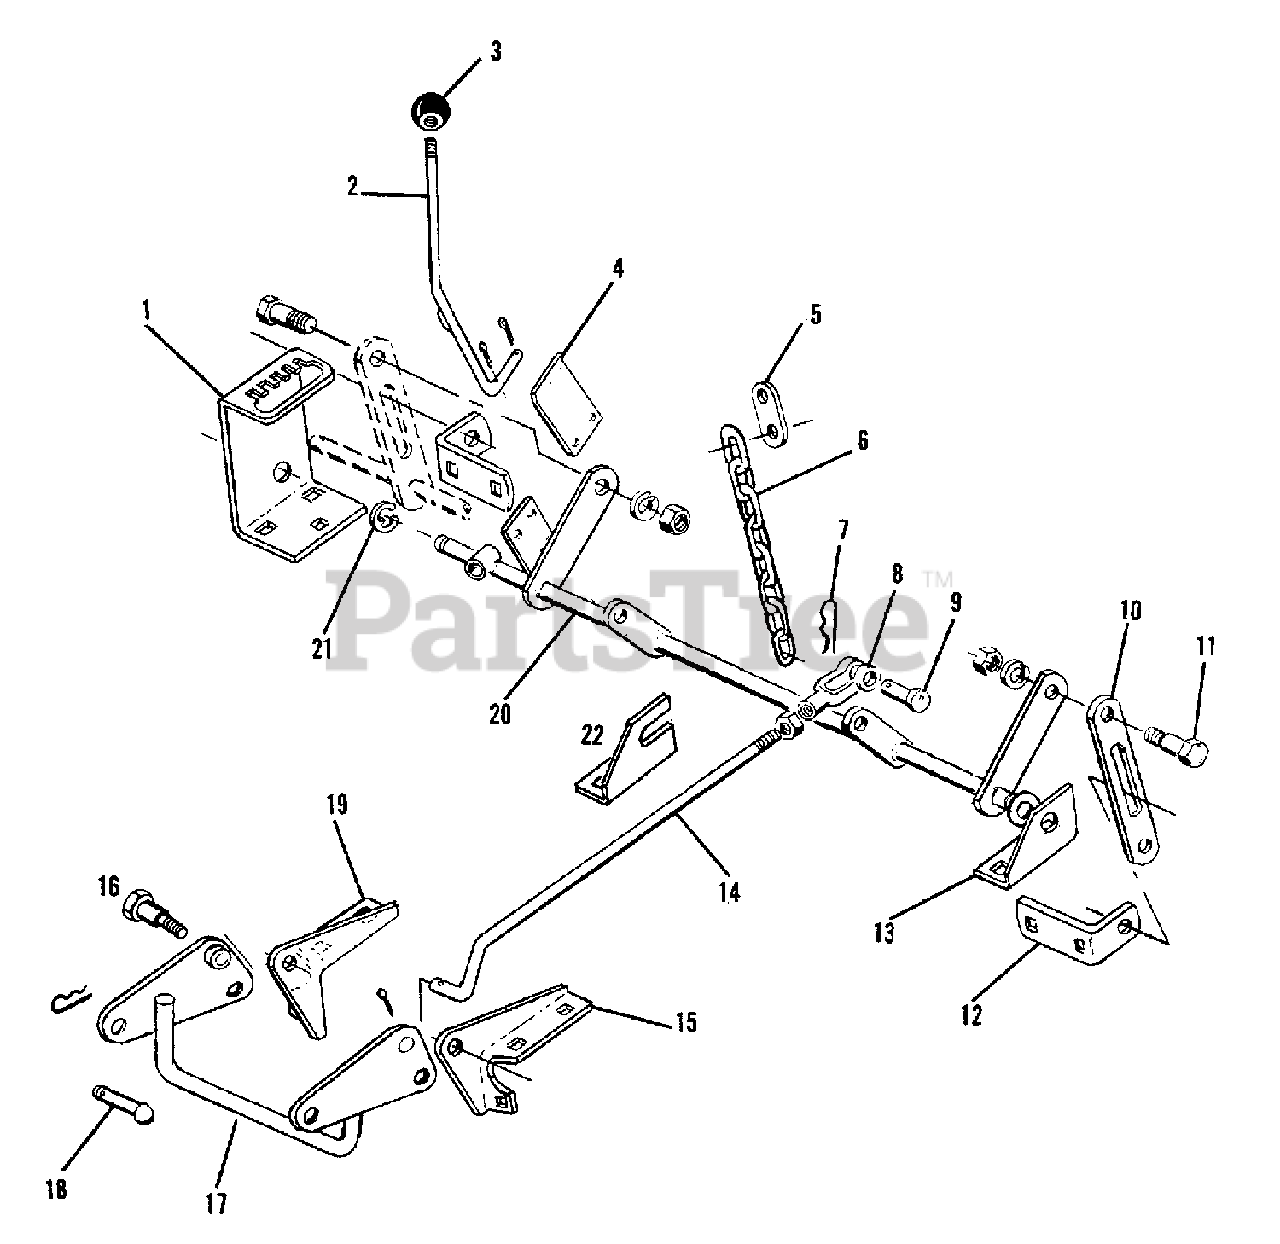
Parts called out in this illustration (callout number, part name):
1	QUADRANT, Control
1	DECAL, Quadrant
1	BOLT, Carriage, 4/8NC x 3/4
1	LOCKWASHER, 3/8
1	NUT, 3/8NC
2	LEVER, Control
2	PIN, Cotter, 1/8 x 1
3	KNOB, Control Lever
4	SPRING, Lever Retaining
4	RIVET, Pop, 3/16
5	LINK, Lift
5	CAPSCREW, 3/8NC x 1
5	WASHER, Plain, 7/16 x 1 x #14
5	NUT, Lock, 3/8NC
6	CHAIN, Lift
6	CAPSCREW, 3/8NC x 1-1/4
6	WASHER, Plain, 7/16 x 1 x #14
6	LOCKWASHER, 3/8
6	NUT, 3/8NC
7	PIN, Quick-Hitch
8	YOKE, Rod
9	PIN, Yoke
10	BAR, Roller Lift
11	BOLT, Shoulder, 3/8-16 X 1.34
11	WASHER, Plain, 1/2 x 1-1/4 x #14
11	LOCKWASHER, 3/8
11	NUT, 3/8NC
12	BRACKET, Roller Support
12	BOLT, Carriage, 3/8NC x 3/4
12	BOLT, Carriage, 3/8NC x 1
12	LOCKWASHER, 3/8
12	NUT, 3/8NC
13	BRACKET, Pivot, L.H.
14	ROD, Adjusting, R.H. (f/42" Mower)
14	ROD, Adjusting, L.H. (f/42" Mower)
14	ROD, Adjusting, R.H. (f/48" Mower)
14	ROD, Adjusting, L.H. (f/48" Mower)
14	PIN, Cotter, 1/8 x 1
14	NUT, Jam 1/2NF
15	BRACKET, Link, L.H.
15	BOLT, Carriage, 3/8NC x 3/4
15	LOCKWASHER, 3/8
15	NUT, 3/8NC
16	BOLT, Shoulder
16	NUT, 3/8NC, Lock
17	LINK ASSEMBLY, Pivot
18	PIN, Link
19	BRACKET, Link, R.H.
19	BOLT, Carriage, 3/8NC x 3/4
19	LOCKWASHER, 3/8
19	NUT, 3/8NC
20	ARM ASSEMBLY, Adjusting
20	WASHER, Plain, 25/32 x 1-1/4 x #16
21	RING, Retaining
22	BRACKET, Lift
22	BOLT, 5/16NC x 3/4
22	LOCKWASHER, 5/16
22	NUT, 5/16NC
22	PIN, Spring, .072 x 1
